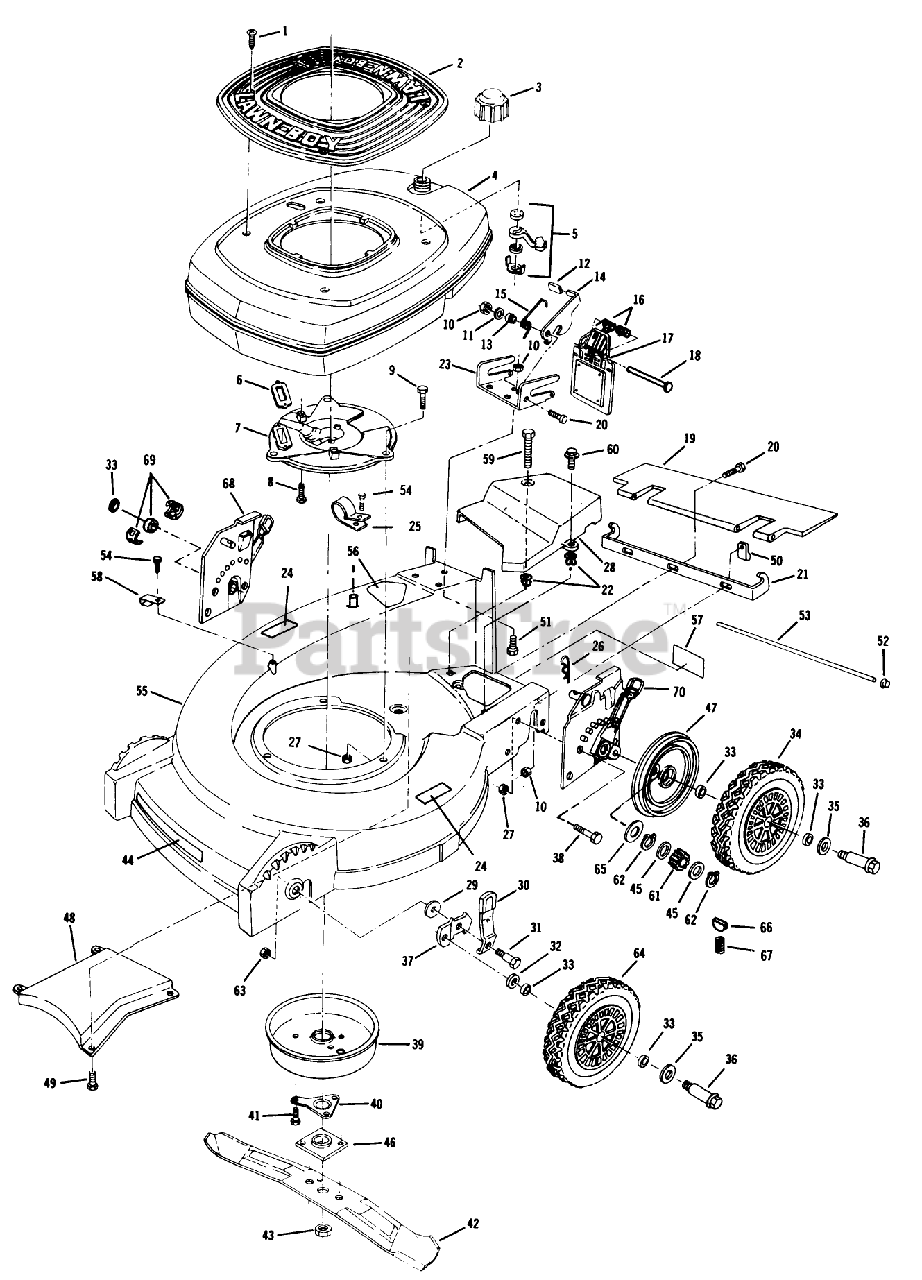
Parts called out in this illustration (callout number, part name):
1	SCREW - SELF TAPPING
3	FUEL CAP & INSERT
5	SHUT-OFF VALVE S
7	PLATE F
8	SCREW V
9	SCREW-HH
10	LOCKNUT E
15	SPRING
16	SPRING ASOC
18	ROD (RB&W)
19	T/SHIELD SM&P
26	HAIR PIN
27	NUT-LOCK F
29	WASHER
31	BOLT
32	WASHER WROUGHT
33	WASHER
35	SPACER
36	BOLT WHEEL
39	MUFFLER COVER F
40	SUPPORT F
41	SCREW
43	NUT-BLADE
45	SPACER/GR ALGHNY
46	PLATE AND COLLAR ASM
48	BAFFLE CHUTE PL
54	SCREW LAWRENCE
60	SCREW
61	PINION BROCKWAY
62	RET RING
63	LOCKNUT
64	WHEEL&TIRE 8" TRI
65	THRUST WASHER
66	KEY
67	SPRING
69	REAR AXLE BEARING
70	HEIGHT ADJUSTER AY
